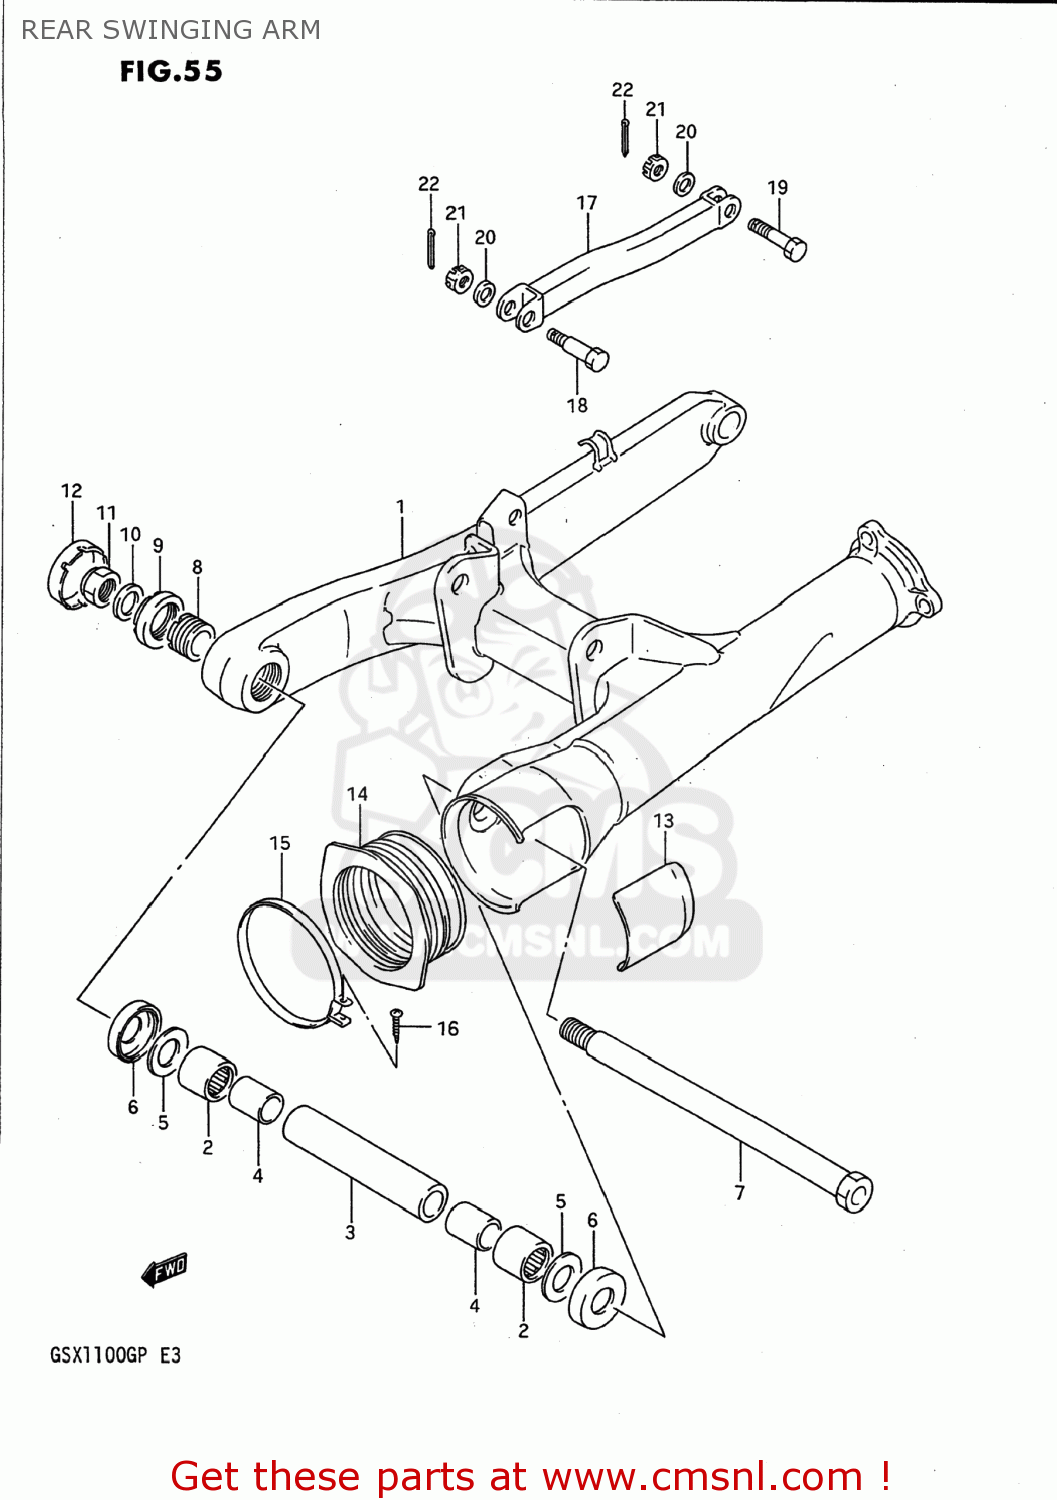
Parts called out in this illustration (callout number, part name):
1	SWING ARM ASSEMBLY,REAR
2	BEARING(25X33X30)
3	SPACER (20.8X27.2X143)
4	SPACER,RR SWGARM PIVOT BERRING
5	WASHER
6	COVER,RR SWGARM PIVOT SEAL
7	SHAFT,REAR SWING ARM
8	BOLT,RR SWGARM PIVOT
9	NUT,REAR SWING ARM PIVOT
10	WASHER (18.2X28X2.6)
11	NUT
12	CAP,SWINGINGARM PIVOT
13	COVER,REAR SWING ARM PIVOT
14	BOOT,PROPELLER SHAFT
15	CLAMP
16	SCREW 4X25
17	TORQUELINK,RR
18	BOLT(10X41)
19	BOLT(10X35)
20	WASHER (10X18X3.2)
21	NUT
22	PIN 20X20
